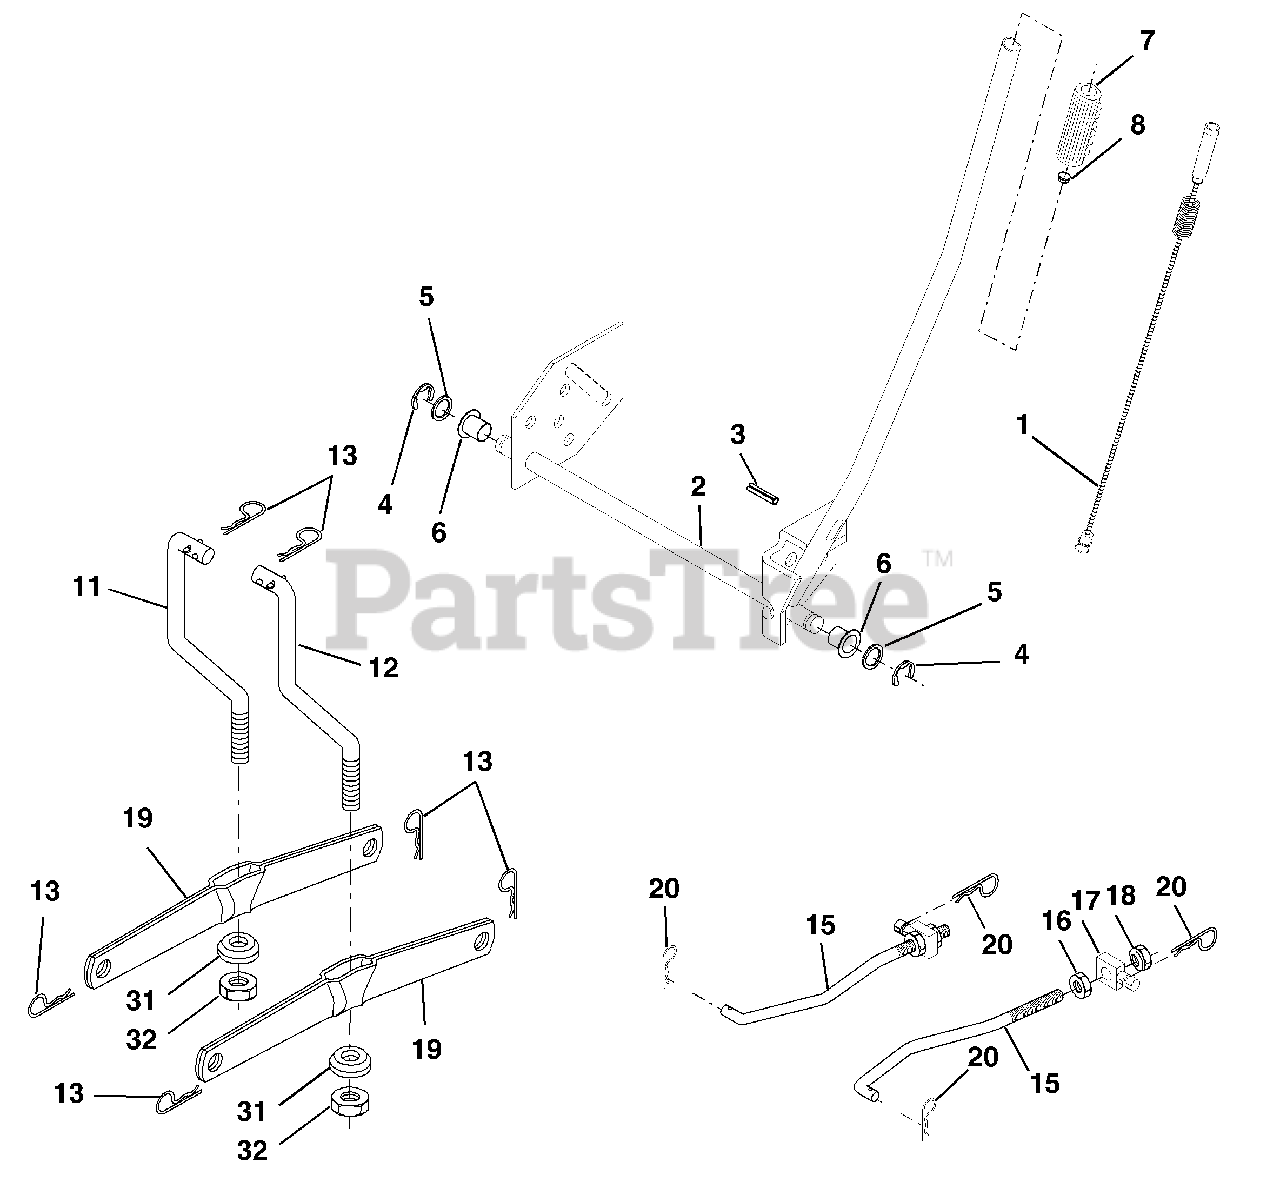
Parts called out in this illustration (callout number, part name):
1	Wire Asm Inner W/plunger
2	Shaft Asm Lift RH w/Inf
3	Pin Groove 1 500 Zinc
4	E Ring #5133-62
5	Washer 21/32 X 1 X 21 Ga
6	Bearing Nylon Blk 629 Id
7	Grip Handle Fluted Blk
8	Button Plunger Black
11	Link Lift LH Fixed Length
12	Link Lift RH Fixed Length
13	Retainer Spring
15	Link Front
16	Nut Jam Hex 1/2-13 Unc
17	Trunnion Blk Zinc
18	Nut Lock w/Wsh 1/2-13unc
19	Arm Suspension Rear
20	Retainer Spring
31	Bearing Pvt Lift
32	Nut Crownlock 3/8 - 24
